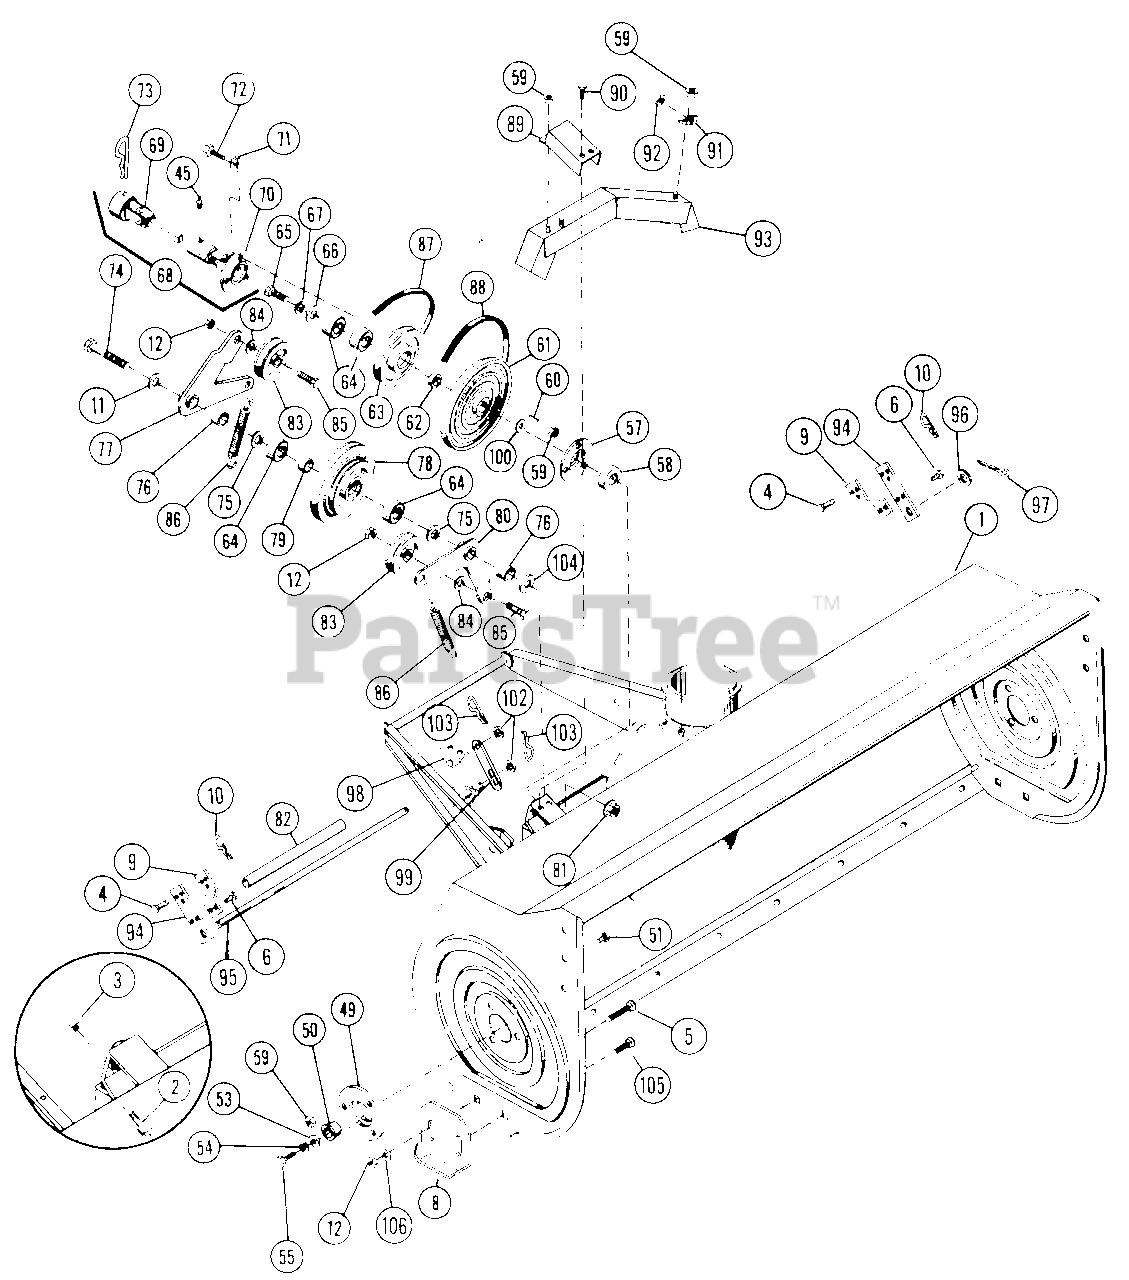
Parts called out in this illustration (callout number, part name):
1	48-INCH SNO THRO HOUSING
2	SCREW, #10-24X.375 CAP
3	NUT, TWIN WHIZ-LOCK #10-24
4	CLEVIS PIN
5	BOLT, 3/8-16X1.00 RD HD SQ NK
6	BOLT, HEX 5/16-18X.50
8	SKID, RUNNER
9	SUPPORT
10	HAIR PIN, INTERNAL 3/32
11	WASHER, .760/.780X1.250X.093
12	NUT, LOCK 3/8-16
45	FITTING, LUBE 1/4-28
49	SUPPORT, BEARING
50	BUSHING, FLANGE 1X1.12X.625
51	BOLT, RIB NECK 1/4-20X.50
53	WASHER, FLAT .515X1.441X.1
54	WASHER, LOCK 1/2 SP HEAVY
55	BOLT, HEX 1/2-13X1.00
57	BEARING, FLANGE
58	BEARING, BALL
59	NUT, LOCK 1/4-20
60	KEY, WOODRUFF .187X.875 HARD #11
61	SHEAVE, 7/8X10
62	SPACER
63	SHEAVE
64	RADIAL BEARING
65	BOLT, HEX 3/8-16X1.00
66	WASHER, FLAT .438X1.000X.083
67	WASHER, LOCK 3/8 REG.
68	SHAFT, UNIVERSAL
69	UNIVERSAL HALF
70	UNIVERSAL HALF
71	WASHER, LOCK 1/4 REG.
72	BOLT, HEX 1/4-20X.875
73	PIN, HAIR INT. .187X3.25
74	BOLT, HEX 3/4-10X5.50
75	WASHER, FLAT .938X1.750X.134
76	SPACER
77	IDLER ARM
78	SHEAVE
79	SPACER
80	IDLER ARM
81	WASHER, .878/.882X2.500X10 GA.
82	TUBE
83	IDLER
84	WASHER, .401/.421X.875X10 GA.
85	BOLT, HEX 3/8-16X1.25
86	SPRING
87	BELT
88	BELT
90	SCREW, TAPTITE 1/4-20X.375
91	CLIP
92	NUT, LOCK 5/16-18
93	BELT GUARD
94	LIFT LINK
95	SHAFT
96	WASHER, FLAT .687X1.312X.122
97	PIN, COTTER .125X1.25
98	LIMITING POST
99	LIMITING ARM
100	WASHER
102	WASHER, FLAT .500X1.250X.083
103	HAIRPIN, INTERNAL
104	WASHER, .750/.760X1.400X.062
105	BOLT, CARRIAGE 3/8-16X.75
106	WASHER, FLAT .406X.812X.065
NS	DECAL, GRAVELY LOGO
NS	DECAL, DANGER FOOT
NS	WARNING WHEEL WEIGHT DECAL
NS	DECAL, AMERICA
